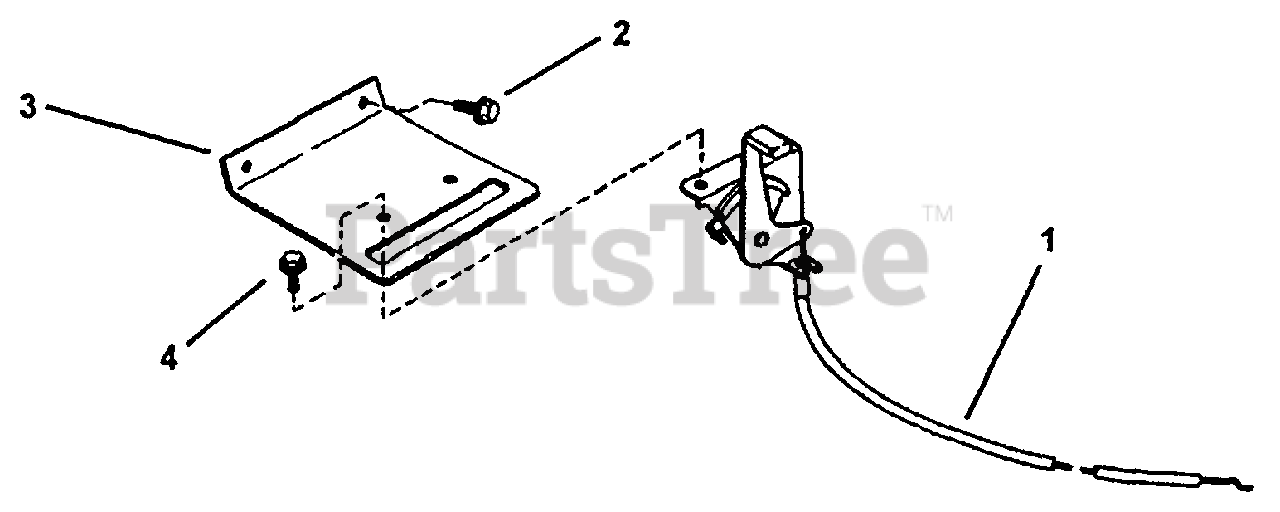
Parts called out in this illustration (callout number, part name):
1	CONTROL, Throttle (23.6" long)
2	SCREW, 1/4-20 x 1/2" Hex Washer Self-Tap
3	PLATE, Throttle Control
4	SCREW, #10-24 x 1/2" Hex Washer Self-Tap (Torx)
